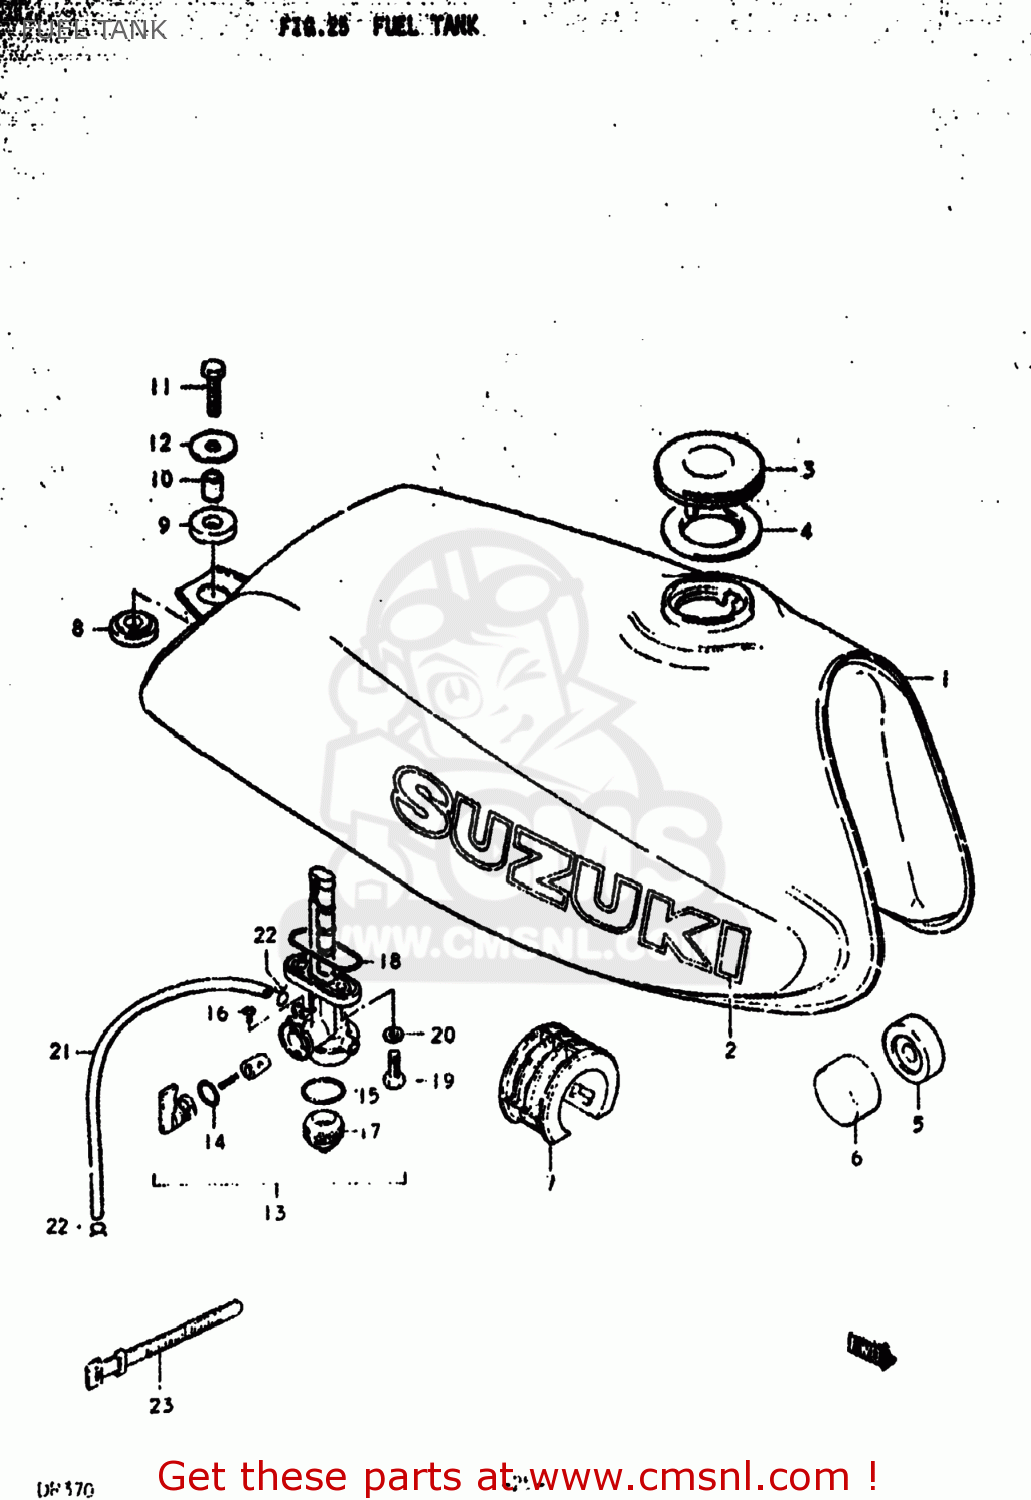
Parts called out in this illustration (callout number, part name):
1	TANK ASSEMBLY,FUEL
2	EMBLEM
3	CAP,FUEL TANK
4	GASKET (NAS)
5	CUSHION
6	CUSHION
7	CUSHION,FUEL TANK
8	BUSH(12X15X20)
9	CUSHION
10	SPACER (8X12X15)
11	BOLT
12	WASHER (8.5X29X1.6)
13	COCK ASSEMBLY,FUEL
14	O-RING
15	GASKET,FILTER (NAS)
16	SCREW,FUEL COCK LEVER
17	CUP,STRAINER
18	O RING,FUEL COCK
19	BOLT L:16
20	GASKET
21	HOSE
22	CLIP
23	CLAMP
